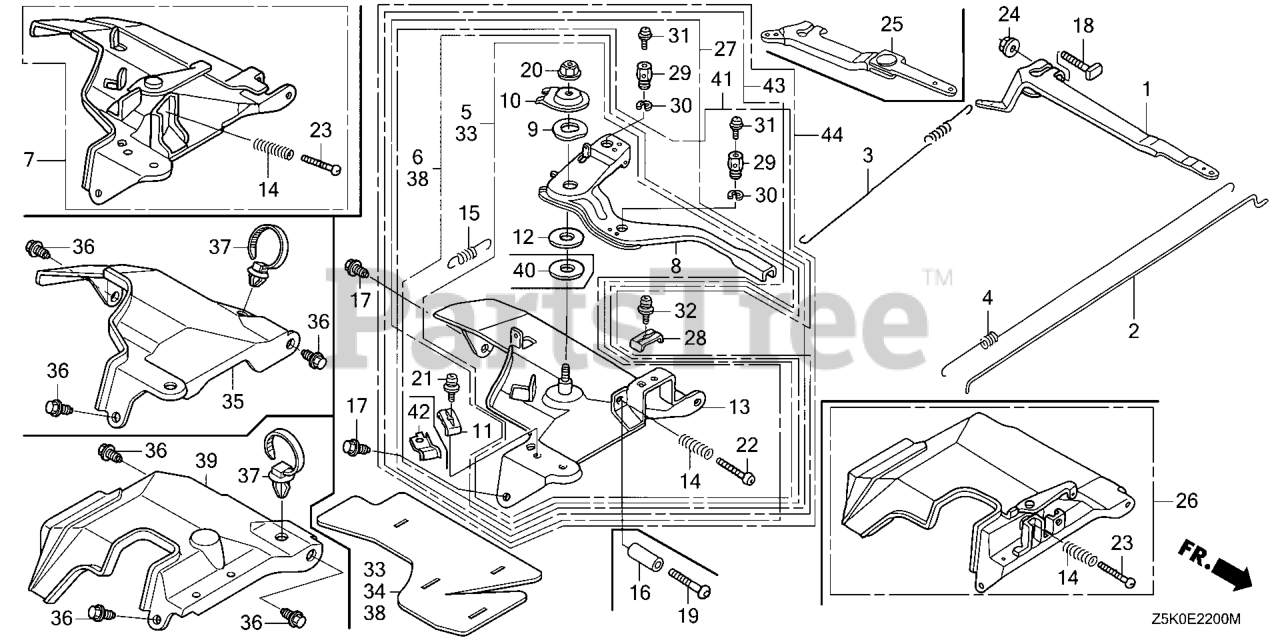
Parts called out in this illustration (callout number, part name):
1	ARM, GOVERNOR
2	ROD, GOVERNOR
3	SPRING, GOVERNOR (L=145.0MM) (WIRE DIAMETER 1.0MM)
4	SPRING, THROTTLE RETURN
6	CONTROL ASSY. (REMOTE)(COO)(FOR U.S.A.)
6	CONTROL ASSY. (REMOTE)
8	LEVER, CONTROL
9	SPRING, LEVER
10	WASHER, CONTROL LEVER
11	HOLDER, CABLE
12	SPACER, CONTROL LEVER
13	BASE, CONTROL
14	SPRING, CONTROL ADJUSTING Use from Engine SN 2327377.
15	SPRING, CABLE RETURN
17	BOLT, FLANGE (6X12) (CT200)
18	BOLT, GOVERNOR ARM
20	NUT, SELF-LOCK (6MM)
21	SCREW, PAN (5X16)
22	SCREW, PAN (5X28)
24	NUT, FLANGE (6MM)
